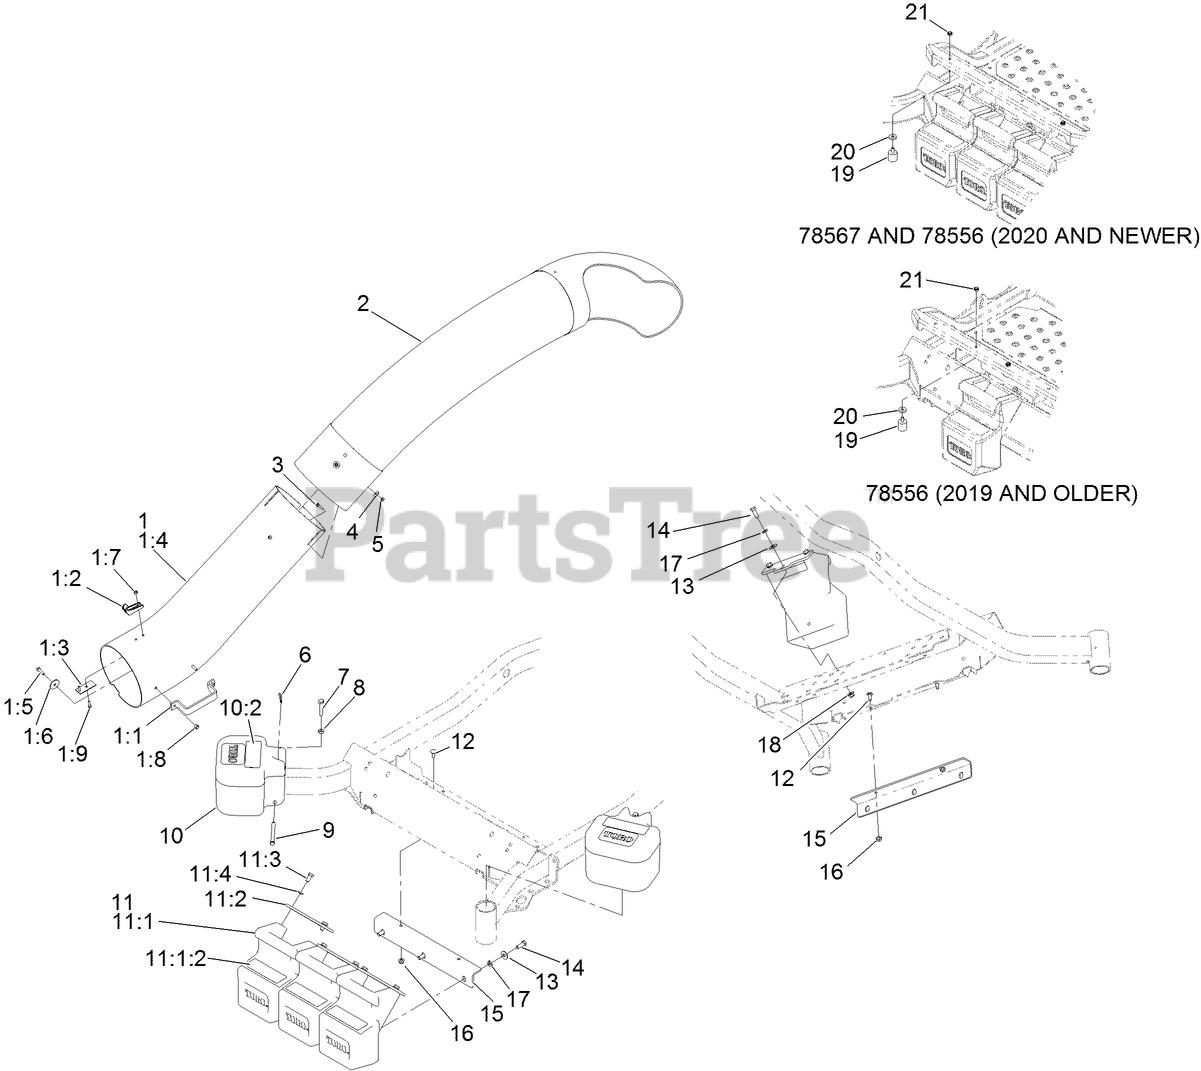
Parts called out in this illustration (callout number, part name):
1	LOWER TUBE ASM
1:2	LATCH-CATCH
1:3	PLATE-BACKING
1:4	TUBE-LOWER
1:5	SCREW-HH
1:6	WASHER-FLAT
1:7	NUT-LOCK, NI
1:8	NUT-LOCK, NI
1:9	SCREW-HWH
2	TUBE-UPPER
3	SCREW-HWH
4	WASHER-FLAT
5	NUT-LOCK, NI
6	PIN-COTTER
7	SCREW-HH
8	NUT-HEX
9	PIN-CLEVIS
10	WEIGHT 62 LBS ASM W/DECAL
10:2	DECAL-WARNING, COUNTERWEIGHT
11	WEIGHT ASM
11:1	WEIGHT W/DECAL ASM
11:1:2	DECAL-WARNING, COUNTERWEIGHT
11:2	TAB-SUPPORT, WEIGHT
11:3	SCREW-HH
11:4	WASHER-LOCK
12	SCREW-CARR
13	WASHER-FLAT
14	SCREW-HH
15	BRACKET-MOUNT, WEIGHT
16	NUT-HF, NI
17	WASHER-LOCK
18	NUT-HF, NI
19	BUMPER-RUBBER
20	SPACER
21	NUT-LOCK, NI
